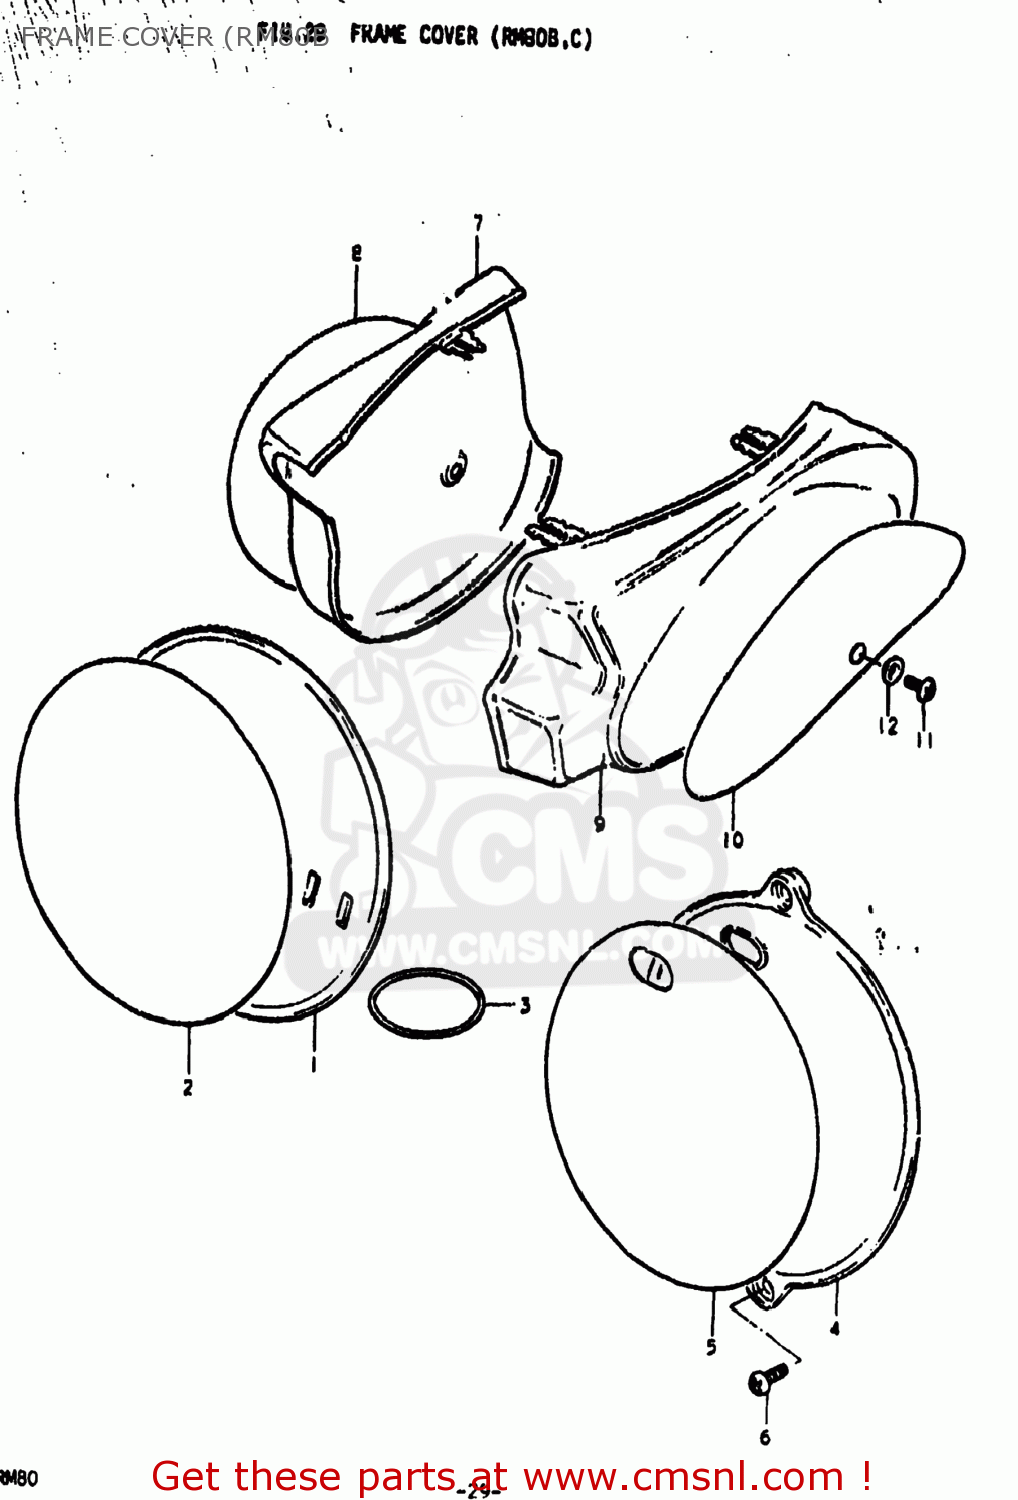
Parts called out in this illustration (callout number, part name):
1	PLATE,NUMBER,FRONT
2	EMBLEM,FRONT NUMBER PLATE
3	O RING(D:3.5,ID:47.7)
4	PLATE,NUMBER,FRONT
5	EMBLEM,FRONT NUMBER PLATE
6	SCREW
7	COVER,FRAME,RIGHT
8	EMBLEM
9	COVER,FRAME,LEFT
10	EMBLEM,FRAME COVER
11	SCREW 6X12
12	WASHER
